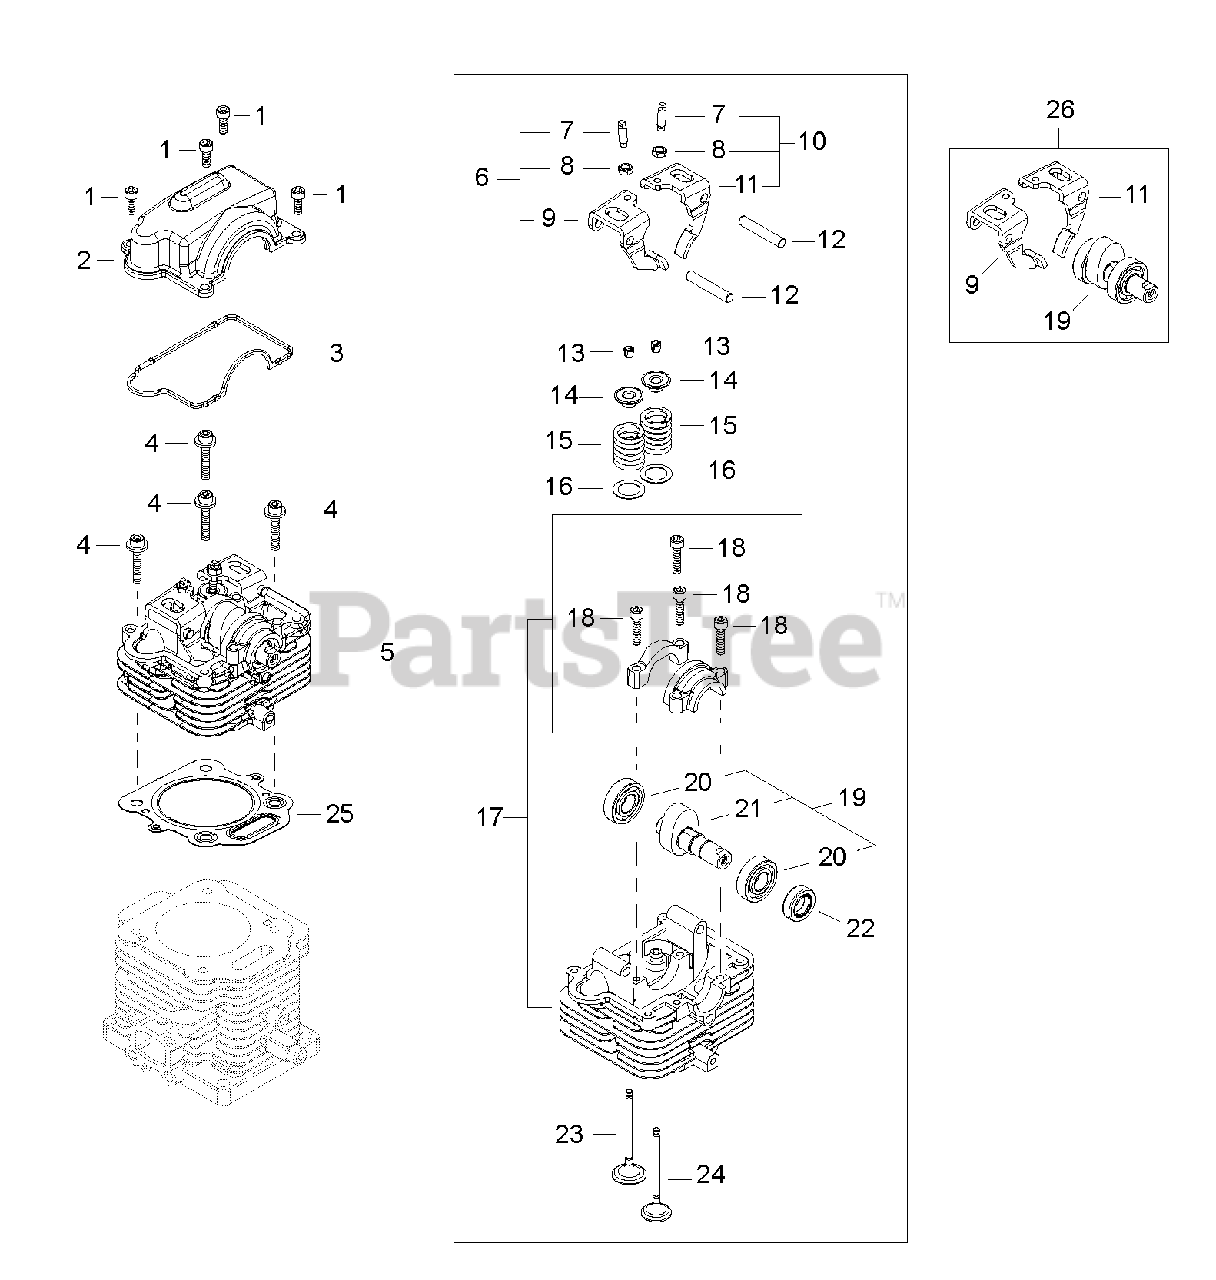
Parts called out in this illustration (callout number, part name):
1	SCREW - 5X16
2	COVER, VALVE
3	GASKET, VALVE COVER
4	SCREW - 6X35 -- FLANGE
5	CYLINDER HEAD ASSY
6	CAM FOLLOWER ASSY A
7	SCREW, ADJUST
8	LOCKNUT, ADJUSTER
9	CAM FOLLOWER A
10	CAM FOLLOWER ASSY B
11	CAM FOLLOWER B
12	ROLLER
13	VALVE KEEPER
14	RETAINER
15	SPRING, VALVE
16	WASHER
17	HEAD, CYLINDER
18	SCREW - 5X22
19	CAMSHAFT ASSY
20	BEARING, BALL - 6001
21	CAMSHAFT
22	SEAL, OIL - 12
23	VALVE, INTAKE
24	EXHAUST
25	GASKET, HEAD
26	CAM KIT
